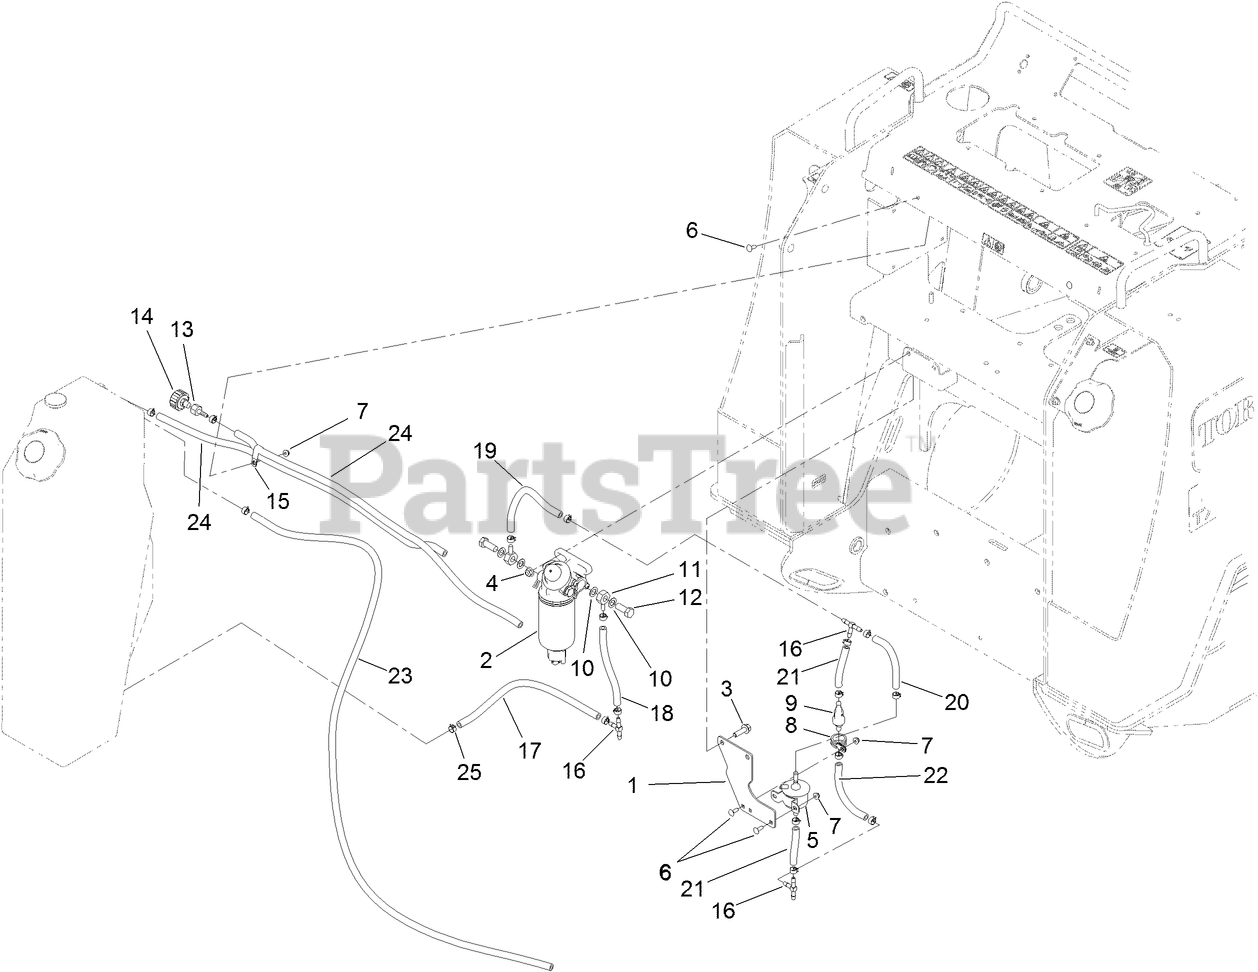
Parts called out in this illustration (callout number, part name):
1	BRACKET-FUEL PUMP
2	FILTER-SEPERATOR, WATER
3	SCREW-HHF
4	NUT-HF, NI
5	PUMP-FUEL
6	BOLT-CARR
7	NUT-HF
8	R-CLAMP
9	VALVE-BYPASS
10	O-RING
11	ADAPTER-FUEL
12	SCREW-ADAPTER
13	FITTING-STRAIGHT
14	BREATHER
15	CLAMP-R, DOUBLE TUBE
16	FITTING-TEE, BARBED
17	HOSE-FUEL
18	HOSE-FUEL
19	HOSE-FUEL
20	HOSE-FUEL
21	HOSE-FUEL
22	HOSE-FUEL
23	HOSE-FUEL
24	HOSE-FUEL
25	CLAMP-HOSE
